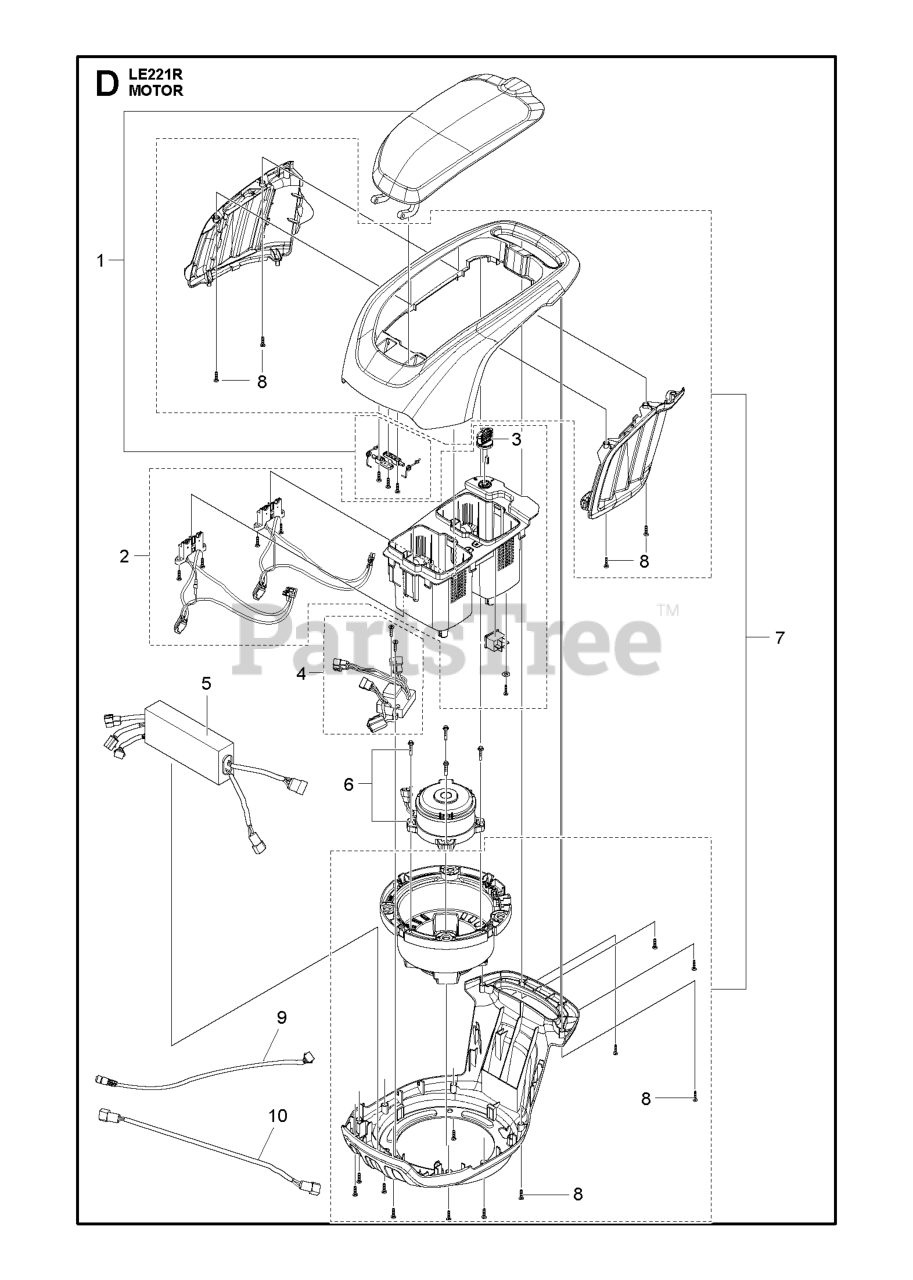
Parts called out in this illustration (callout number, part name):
1	LID ASSY SPARE PART ASSY LC247
2	BATTERY BOX SPARE PART ASSY LC
3	KEY
4	CONTACT PLATE SPARE PART ASSY
5	CONTROL UNIT FOR POWER UNIT LE
6	MOTOR
7	ENGINE HOOD ASSY POWER UNIT LC
8	SCREW SELF TAPPING DAYE# A2680
9	CABLE HANDLE LE121P / LE221R
10	CABLE TRANSMISSION LC347VLI
